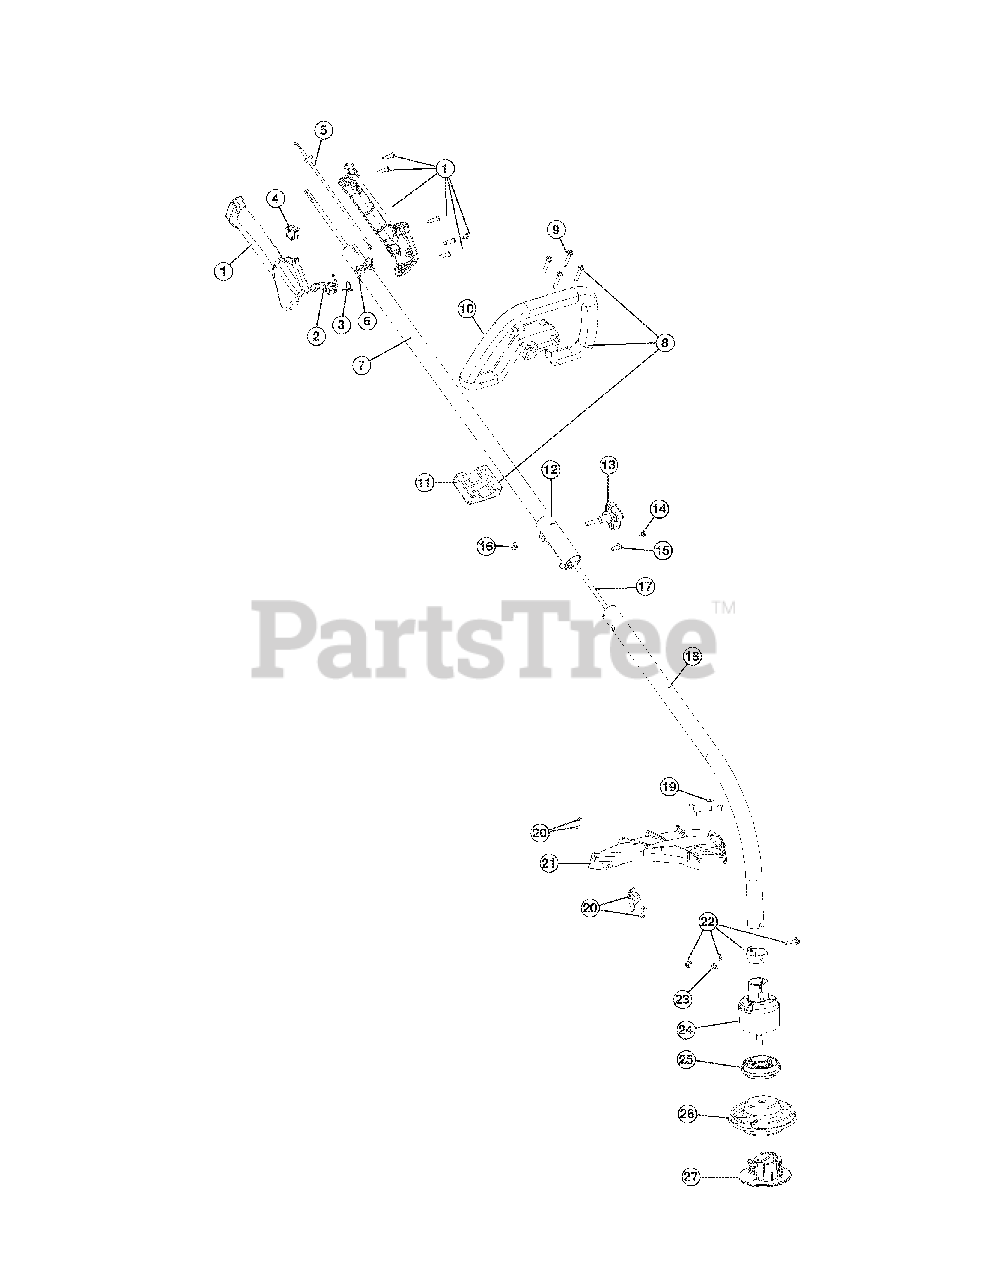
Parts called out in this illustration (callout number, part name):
1	Throttle Housing Assembly (includes 2-4)
2	Throttle Trigger
3	Throttle Trigger Spring
4	Switch Assembly
5	Throttle Cable Assembly
6	Harness Clip
7	Upper Drive Shaft Housing
8	Deluxe D-Handle Assembly (includes 9-11)
10	D-Handle
11	D-Handle Base
12	Twist Boom Coupler (includes 13-16)
13	Adjustment Knob (includes 16)
16	Nut
17	Flexible Drive Shaft
18	Lower Drive Shaft Housing
19	Shield Mount Hardware
20	Blade Assembly
21	Shield Assembly (includes 20)
22	Lower Clamp Assembly
23	Anti-Rotation Screw
24	Bushing Housing Assembly
25	Adapter
26	Cutting Head Assembly
26	Cutting Head Cap
